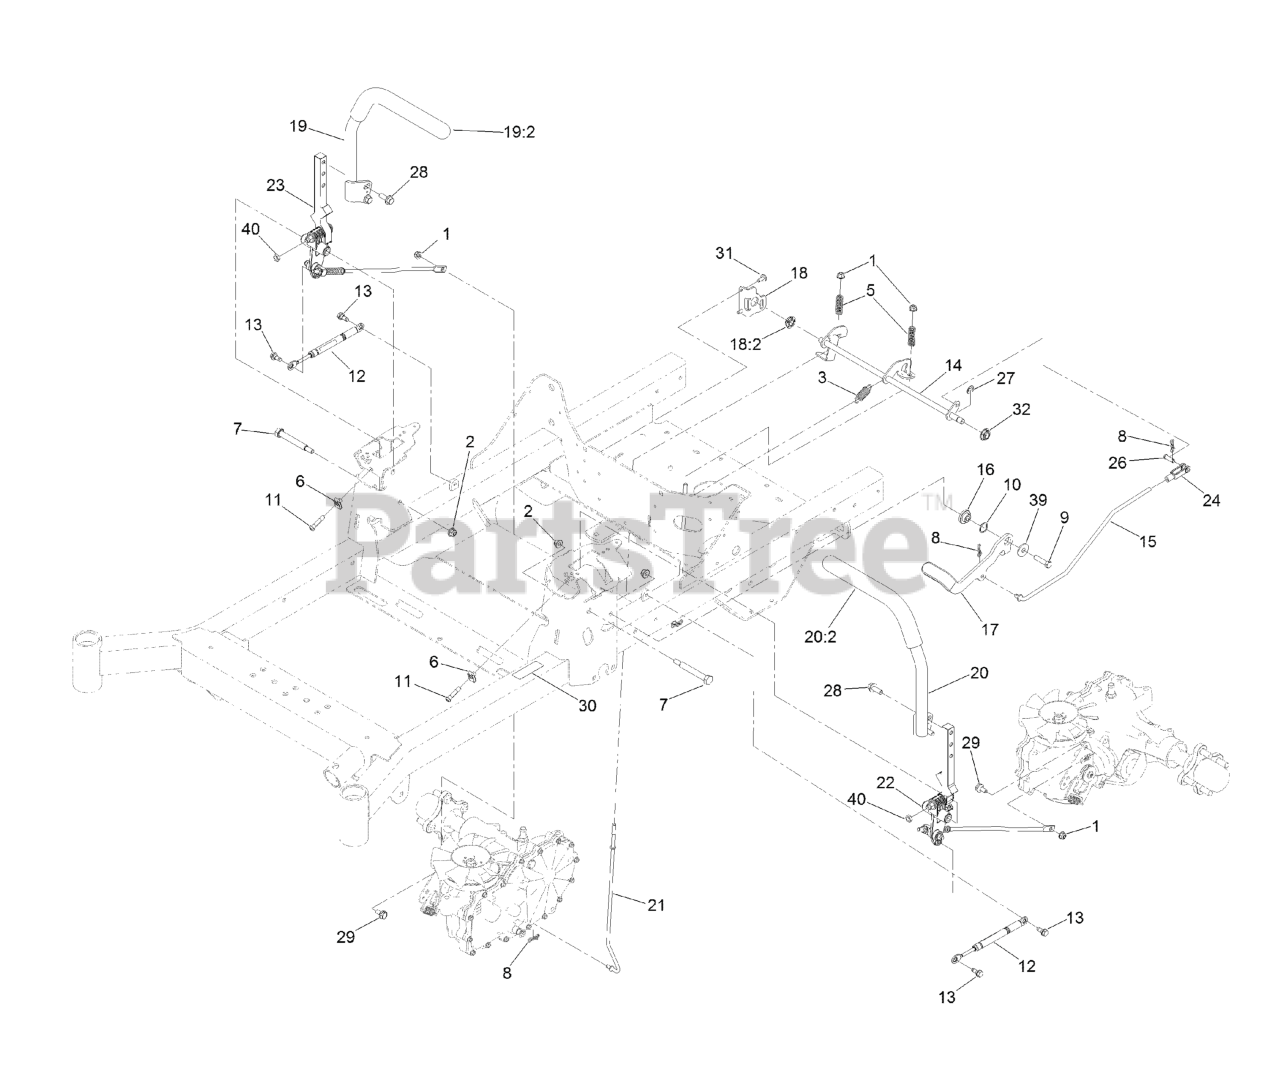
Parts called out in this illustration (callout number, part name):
1	NUT-HF, NI
2	NUT-HF, NI
3	SPRING-EXTENSION
5	SPRING-COMPRESSION
7	BOLT-PIVOT
8	PIN-COTTER, LOCKING
9	SCREW-HH
10	WASHER-WAVE
11	SCREW-HSBH
13	SCREW-SHOULDER
14	SHAFT-BRAKE
15	LINKAGE-BRAKE, UPPER
16	PIVOT-FLANGE
17	LEVER-BRAKE (WITH GRIP)
18	BRACKET-BRAKE
18:2	BEARING-SPHERICAL
19	RH CONTROL HANDLE ASM
20	LH CONTROL HANDLE ASM
21	LINKAGE-BRAKE, LOWER
22	LH Motion Control ASM
23	RH Motion Control ASM
24	YOKE-ADJUSTABLE
26	PIN-CLEVIS
27	RING-RETAINING, EXTERNAL
28	SCREW-HHF 3/8-16 X 1
29	BOLT-SHOULDER,HFH
30	DECAL-BRAKE, PARKING
31	SCREW-TORX
32	BEARING-SPHERICAL
39	WASHER
40	NUT-JAM
